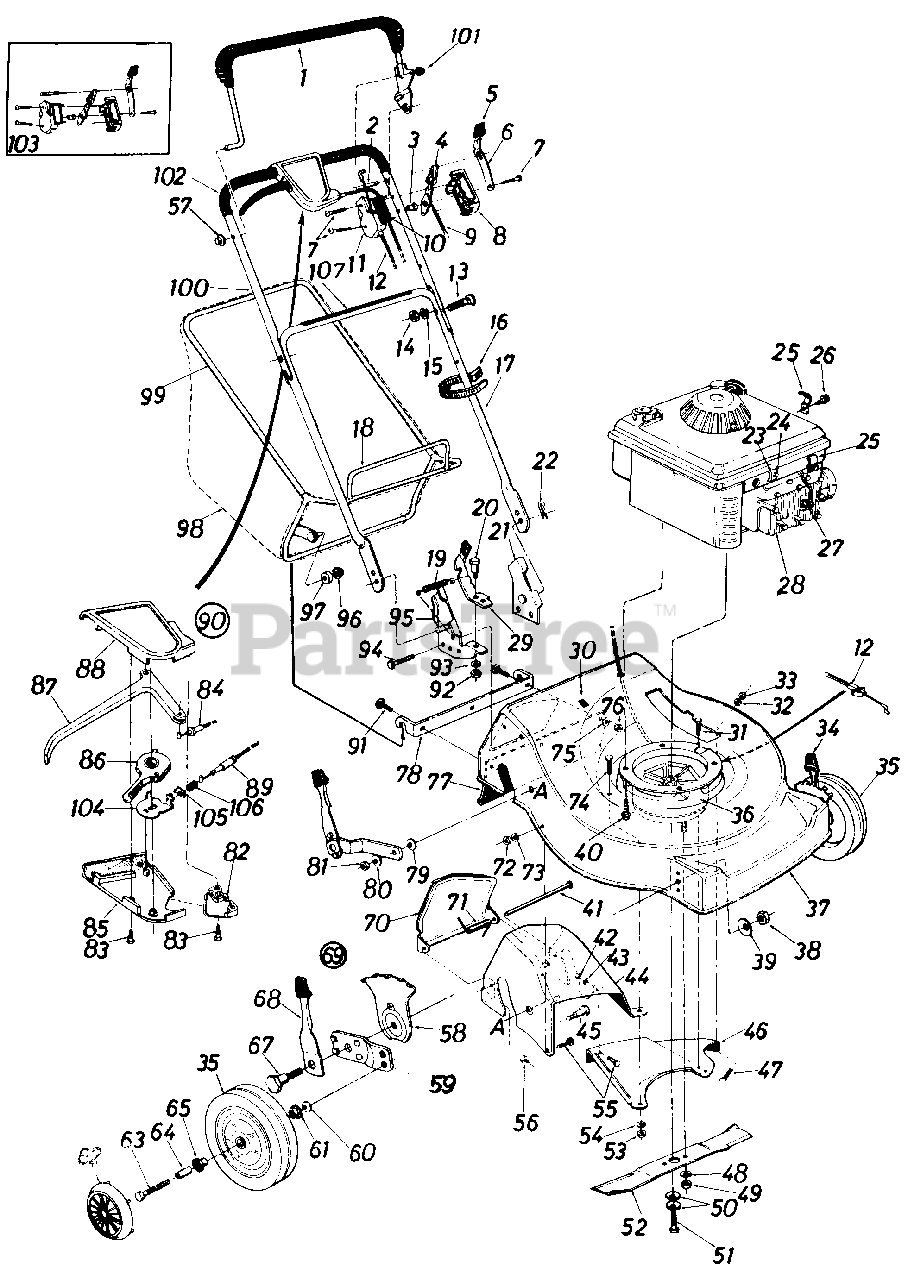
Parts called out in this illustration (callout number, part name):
1	L.H. Bail Ass'y.
2	Lock Pin
3	Control Disc Pin
4	Throttle Control Lever
5	Spring Lever Knob
6	Lockout Spring
7	Truss Mach. Hi-B Tap Scr. #12 x 1.50" Lg.
8	Control Panel Half
9	Throttle Control Wire
10	Control Label
11	Clutch Panel Half
12	Clutch Cable 46" Lg.
13	Carr Bolt 5/16-18 x 1.38"
14	Hex Nut 5/16-18 Thd.*
15	L-Wash. 5/16" I.D.
16	Cable Tie
17	Lower Handle
20	Shld. Bolt .437" Dia. x .162
21	Handle Brkt. Ass'y.-L.H.
22	Hairpin Cotter 5/16" Dia.
23	Hex B-Tap Scr. #10 x .62"
24	Casing Clamp
25	Cable Clip
26	Hex B-Tap Scr. #10 x .38"
27	Spark Plug Insulator
28	Engine
29	Catcher Lock Lever w/Knob
31	Hex TT-Tap Scr. 1/4-20 x .75" Lg.
32	L-Wash. 1/4" I.D.
33	Hex Nut 1/4-20 Thd.
34	Height Adj. Ass'y.-L.H.
35	Front Wheel Ass'y. Comp.
36	Blade/Brake Clutch Ass'y.-Comp.
39	Bell-Wash. .39" I.D. x 1.13"
40	Hex Wash. Hd. TT-Tap Scr. 3/8-16 x 1.0" Lg.
41	Hinge Pin
42	Hex Nut 1/4-20 Thd.
43	L-Wash. 1/4" I.D.
44	Rear Chute-R.H.
45	Shld. Bolt.500" Dia.
46	Rear Baffle-L.H.
47	Carr. Bolt 1/4-20 x 50" Lg.
48	L-Wash. 3/8" I.D.
49	Hex Nut 3/8-24 Thd.-Gr. 8
50	Bell-Wash. 40" I.D. x .88"
51	Hex Cl-Bolt 3/8-24 x 2.0" Lg. (Grade 8)
52	22" Blade
53	Hex Nut 1/4-20 Thd.
54	L-Wash. 1/4" I.D.
55	Carr. Bolt 1/4-20 x .50" Lg.
56	Hex Sems Nut 1/4-20 Thd.
57	Push Cap
58	Height Adj. Plate
59	Wheel Pivot Bar
60	Bell-Wash. .40" I.D. x .88"
61	Bearing
62	Plastic Hub Cap
63	Axle Bolt
64	Spacer
65	Bearing
67	Shld. Bolt .50" Dia. x .430
68	Spring Lever Ass'y. w/ Knob
69	Height Adj. Ass'y.-R.H.
70	Chute Door
71	Torsion Spring
72	Hex Nut 1/4-20 Thd.*
73	L-Wash. 1/4" I.D.
74	Hex Bolt 1/4-20 x .88" Lg.
75	Fl-Wash. .285" I.D. x 1.25"
76	Hex Sems Nut 1/4-20 Thd.
77	Rear Flap
78	Grass Catcher Hitch Brkt.
79	Bell-Wash. 40" I.D. x 1.13"
80	Bell-Wash. 40" I.D. x .88"
81	Hex Jam Nut 3/8-16 Thd.
82	Cable Mounting Cap
83	Flat "C"-Sunk Hd. Tap Scr. #10 x .75" Lg.
84	S.P. Cable- 53" Lg.
85	3-Sp. S.P. Control-Lower Cover
86	Shimano 3-Sp. Shift Lever
87	Control Lever
88	3-Sp. S.P. Control- Upper Cover
89	Shimano 3-Sp. Solid Shift Cable
90	Clutch Control Hsg. Comp.
91	Carr. Bolt 1/4-20 x 75n Lg.*
92	Hex Nut 5/16-18 Thd.*
93	L-Wash. 5/16" I.D.*
94	Hex L-Wash. Hd. AB-Tap Scr. 1/4" x 62" Lg.
95	Handle Brkt. Ass'y.-R.H.
96	Push Nut 3/8" Rod
97	Plastic Roller
98	Grass Bag (w/o Flip Top)
99	Catcher Upper Frame
100	Upper Handle
101	Push Cap
103	Control Housing Comp.
104	Shimano 3-Sp. Shift Lever Brkt.
105	Shimano 3-Sp. Cable Spring Brkt.
106	Shimano 3-Sp. Cable Mounting Spring
107	Instruction Label
